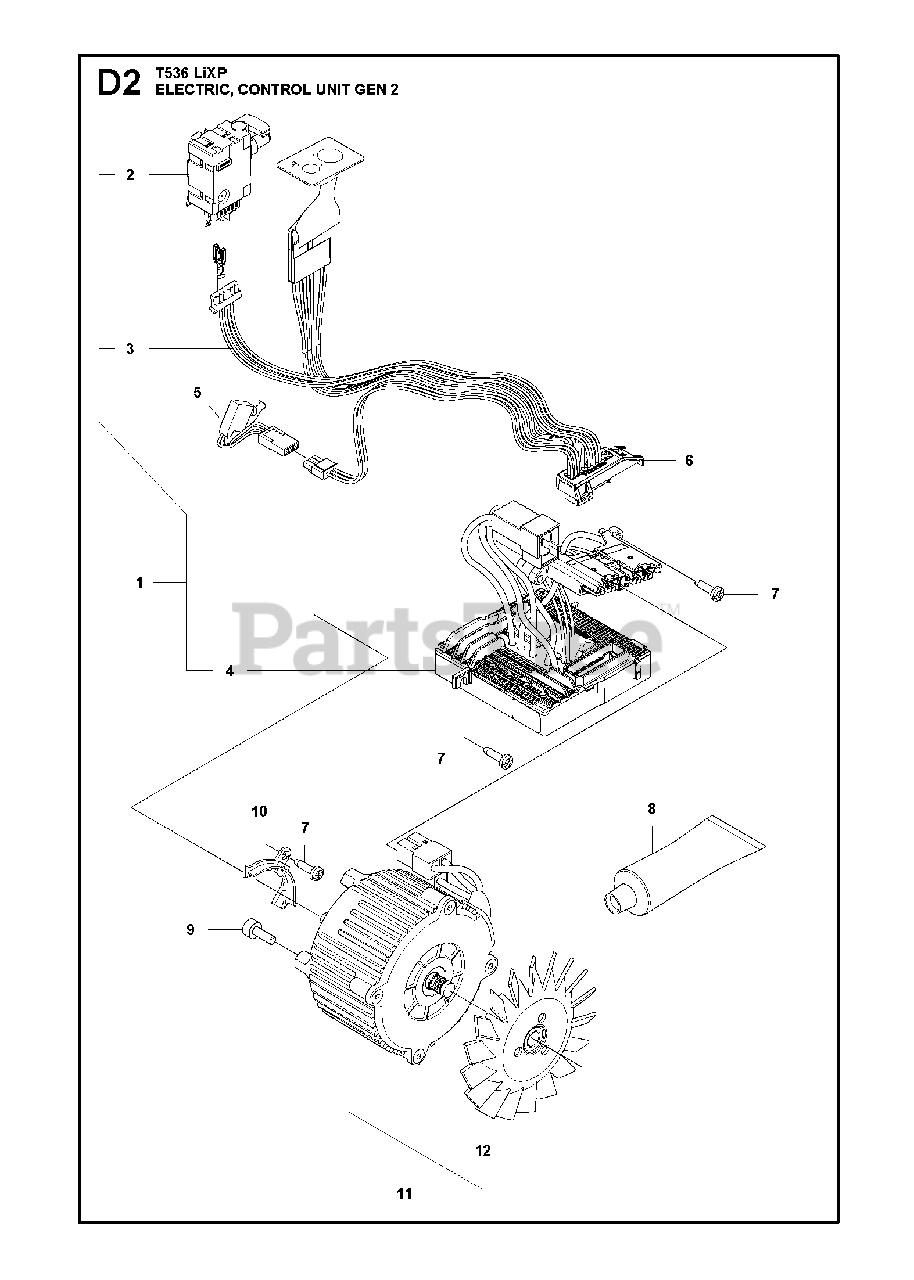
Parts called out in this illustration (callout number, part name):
1	CONTROL UNIT
2	TRIGGER SWITCH
3	WIRING ASSY SIGNAL TOPHANDLE
4	CONTROL UNIT
5	WIRING ASSY
8	GREASE TUBE Q8 RUYSDAEL WR2
11	MOTOR ASSY BLDC D70
